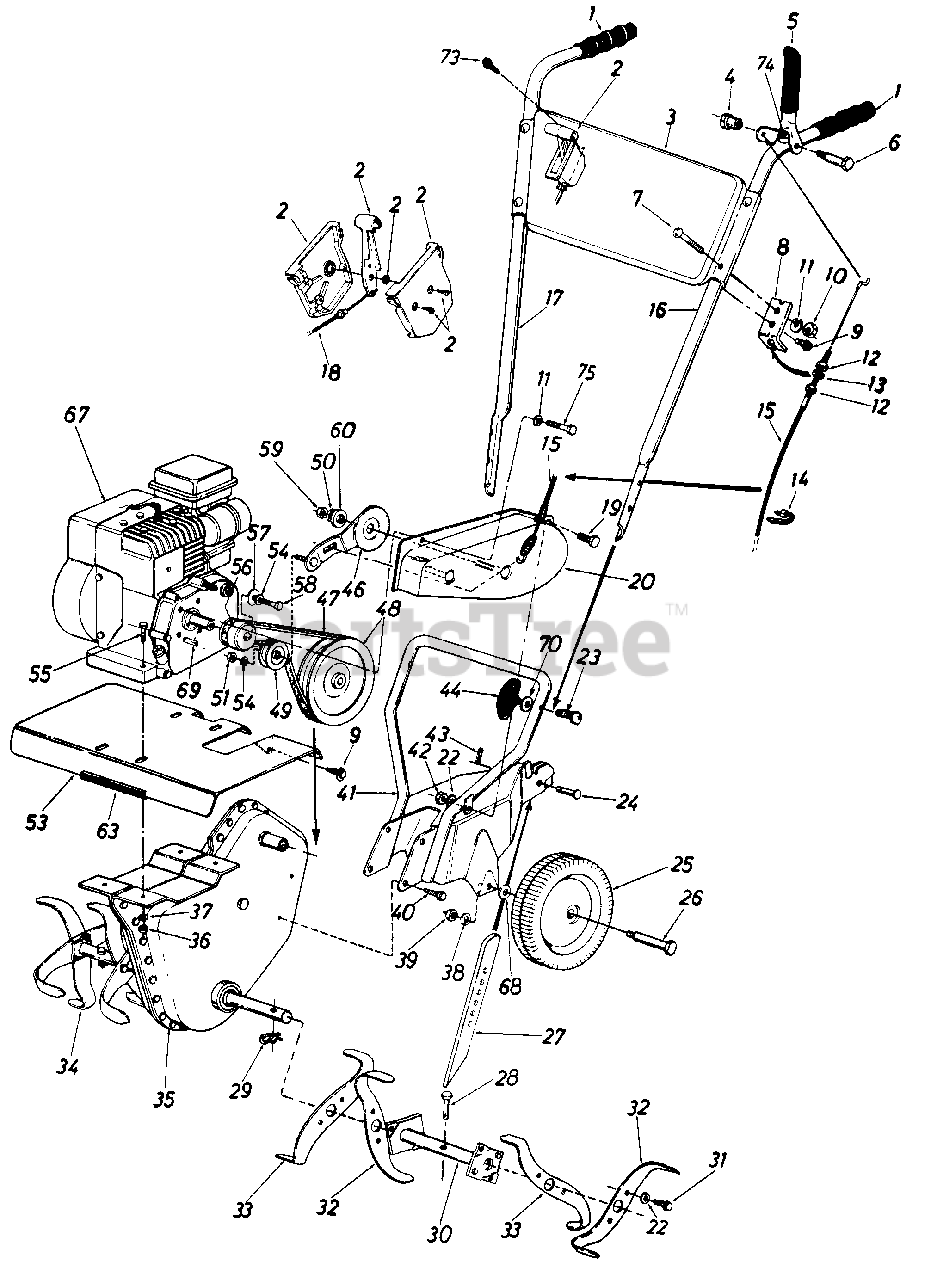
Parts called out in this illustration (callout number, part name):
2	Throttle Control Box Ass'y.
3	Handle Panel
4	Shoulder Nut
5	Clutch Grip Ass'y.
6	Shoulder Bolt 3/8" x 1.16"
7	Carriage Bolt 5/16-18 x 1.5" Lg.
8	Cable Support Bracket
9	Hex Wash. Hd. Self-Tap Scr. 1/4-20 x .50" Lg.
10	Hex Nut 5/16-18 Thd.
11	L-Wash. 5/16" I.D.
12	Hex Jam Nut 5/16-24 Thd.
13	L-Wash. 5/16" I.D.
14	Cable Tie
15	Clutch Control Cable
19	Hex Bolt 1/4-20 x .62" Lg.
23	Curved Hd. Bolt 5/16-18 x 1.75" Lg.
24	Clevis Pin
25	Wheel Ass'y. Comp.-Steel
26	Shoulder Bolt
27	Depth Bar
28	Clevis Pin .31" Dia. x 1.5"
29	Hairpin Cotter
34	Tine Ass'y. Comp.
35	Chain Case Ass'y. Comp.
36	Hex Nut 5/16-18 Thd.
37	L-Wash. 5/16" I.D.
38	L-Wash. 3/8" I.D. (Heavy Duty)
39	Hex Cent. L-Nut 3/8-16 Thd.
40	Hex Wash. Hd. Self-Tap Scr. 5/16-18 x .50" Lg.
43	Internal Cotter Pin
44	Hand Knob
46	Idler Arm Ass'y.
47	Belt
48	Chain Case Pulley 5 1/2" x 1/2"
49	Fl-Idler 2"
50	L-Wash. 5/16" I.D.
51	Hex Nut 3/8-24 Thd.
55	Hex Bolt 5/16-18 x 1.5" Lg.
56	Engine Pulley 3/8" V
57	Fl-Wash. .385" I.D. x 1" O.D.
58	Hex Bolt 3/8-24 x 1" Lg.
59	Hex Nut 5/16-18 Thd.
60	Shld. Spacer .50" Dia.
63	Trim Strip-4 1/2"
67	Engine
68	Bell-Wash.
69	Square Key 3/16" x 3/4" Lg.
70	Bell-Wash.
73	Self-Tap Screw #10 x .5" Lg.
74	Trim Strip-3/4" Lg.
75	Hex Bolt 5/16-24 x .50" Lg.
04765-0637	TINE SHIELD - POWDER BLACK (0637)
